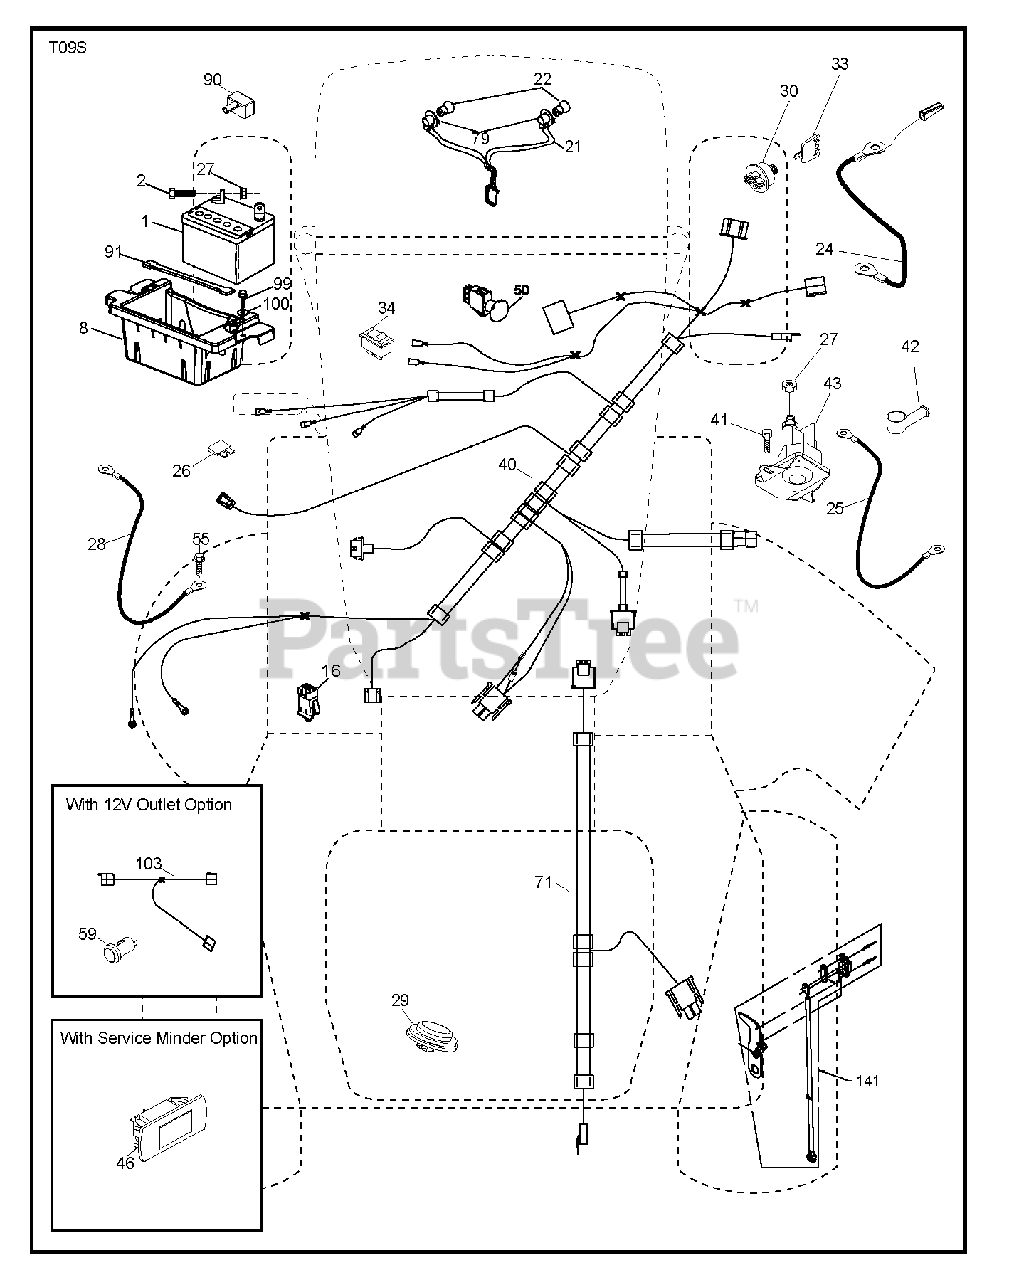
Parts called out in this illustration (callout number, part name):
1	Battery, Dry 30 Amp
2	BOLT.HEX.1/4.X.3/4.DICHROMATE
8	BOX.BATTERY.MOUNT.FRONT.LT
16	SWITCH INTERLOOK PUSH-IN
21	HARNESS.LIGHT W/4152J BULBS
24	CABLE.BATT.POS.WIRE.TG.DA SOL
25	CABLE.STARTER.6G.BL/RED.17.5
26	FUSE 20AMP
27	NUT
28	CABLE GROUND 6 GA 21" 90T BLK
29	SWITCH.SEAT.DELTA.OPC.
30	SWITCH.IGN.DELTA.W.LGH.ROS
33	KEY.CHAIN.BLISTER.PACK.GEN.USA
40	HARNESS.IGN.DASH.HUQ/P
41	SCREW
42	TERMINAL COVER
43	SOLENOID.W/BRASS.PLUNGER
46	RP GUAGE.SRVCMNDR.HRMTR.
50	RB PTO.SWITCH.8 TERMINAL.BLACK
55	SCREW 5/16"
71	HARNESS-CHASSIS SUB
79	BULB HOLDER ASM.
90	COVER.TERMINAL.BATTERY
91	STRAP.BATTERY.MOUNT.FRONT(2 2)
99	SCREW HEXWSHR 1/4-20X3/4
141	KIT.G700/G730.ROS 71750
